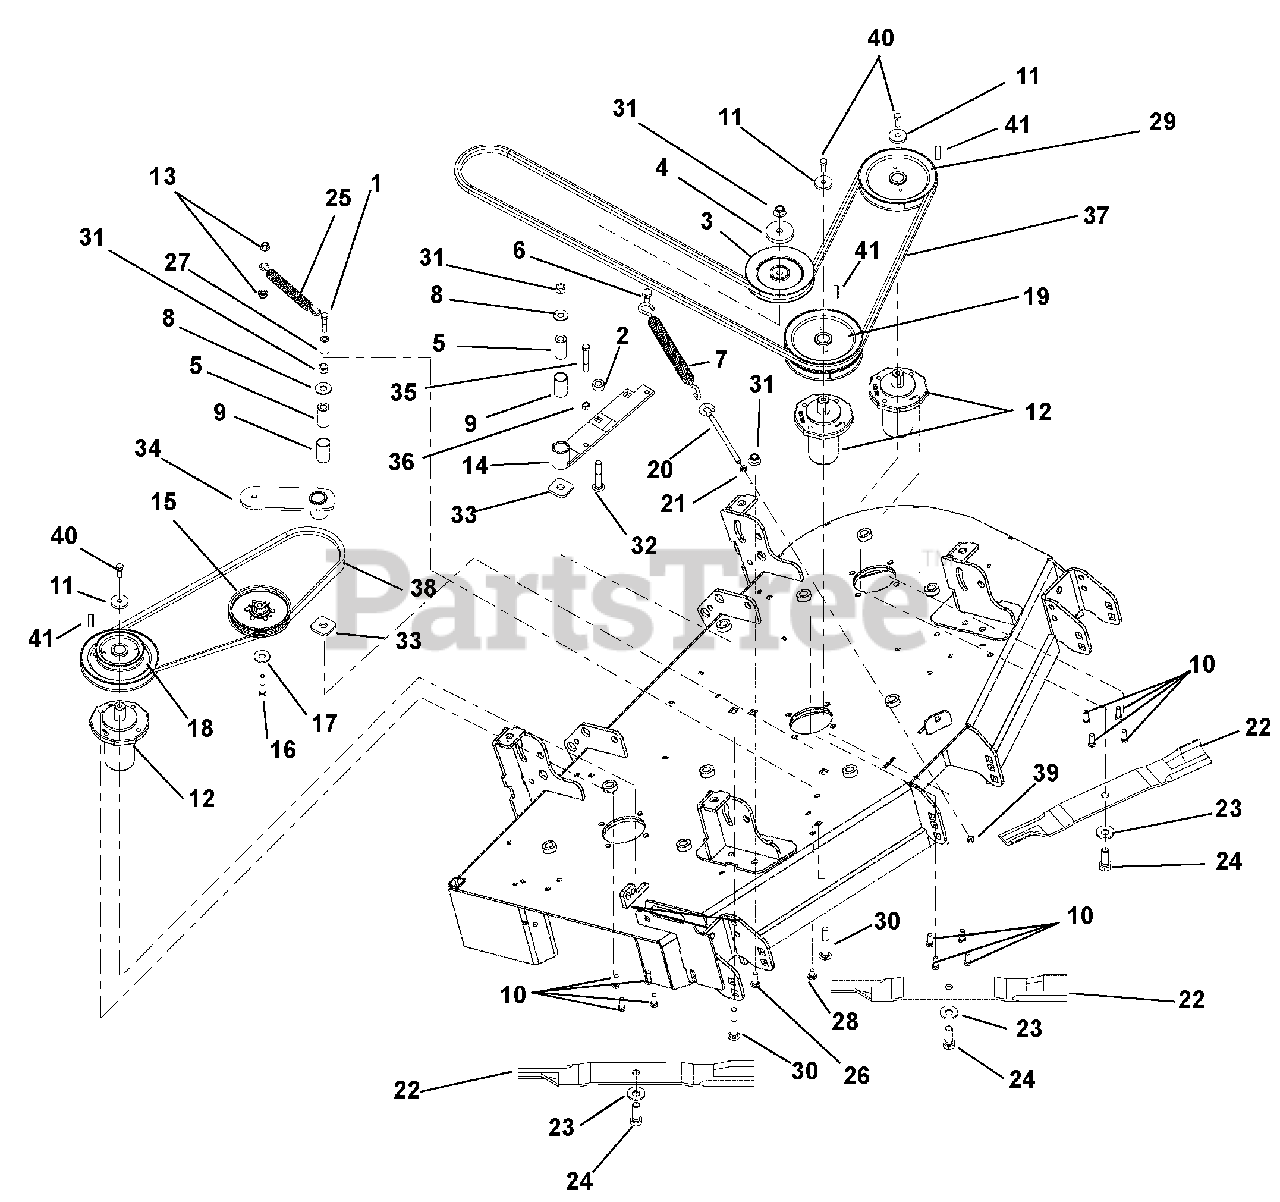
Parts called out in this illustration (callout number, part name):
1	Bolt, Hex .38-16 x 1.50
2	Bushing, Spacer .502 x .997 x .50
3	Sheave, .50 ID x 6.00 OD V-Idlerg
4	Cap, Idler Bearing Sealing
5	Bushing, Spacer .505/.500 x .999/.996 x 2.05/2.03
6	Bolt, Shoulder EP .38-16 x .30 Hex
7	Spring, Extension (Deck Idler)
8	Washer, Flat Steel .563 x 1.38 x .109
9	Bushing, 1.00 x 1.125 x 1.936
10	Bolt, Hex .38-16 x 1.00
11	Retainer, Sheave
12	Assembly, Spindle
13	Nut-Locking-Center .38-16
14	Weldment, Idler Arm
15	Sheave, .38 ID x 5.00 OD V-Idler
16	Bolt, Hex .38-16 x 2.25
17	Washer, Flat Steel .406 x .812 x .065
18	Pulley, Double 1 ID x 5.75 x 3.50 OD
19	Pulley, Double 1.0 ID x 5.75 OD
20	Bolt, .38-16 x 5.50 .62 Diameter Eye
21	Nut, Hex, Jam .375-16
22	Blade, Mulch 16.25
23	Washer, Belleville .63 x 1.625 x .14
24	Bolt, Hex .62-18 x 1.75 Grade 8 (Torque to 115-125 ft. lbs.)
25	Spring, Extension
26	Bolt, Round Head Square Neck .50-13 x 1.5, Full Thread
27	Nut, Coupling .375-16 x 1.75
28	Bolt, Round Head Square Neck .38-16 x 1.00
29	Pulley, V 1 ID x 5.75 OD
30	Bolt, Round Head Square Neck .50-13 x 3.50
31	Nut, .50-13 Nyloc Flange
32	Bolt, Round Head Square Neck .50-13 x 3.00
33	Washer, Flat .640 x 1.75 x .250
34	Weldment, Idler Arm
35	Bolt, Hex .38-16 x 2.75
36	Nut, Hex .38-16
37	Belt, BB 118.00 Wrapped Hex
38	Belt, B 51.18 Raw Cogged
39	Nut, Locking-Center-Jam .375-16
40	Bolt, Hex .38-16 x 2.75 Grade 8
41	Key, Square .25 x .25 x 1.00
